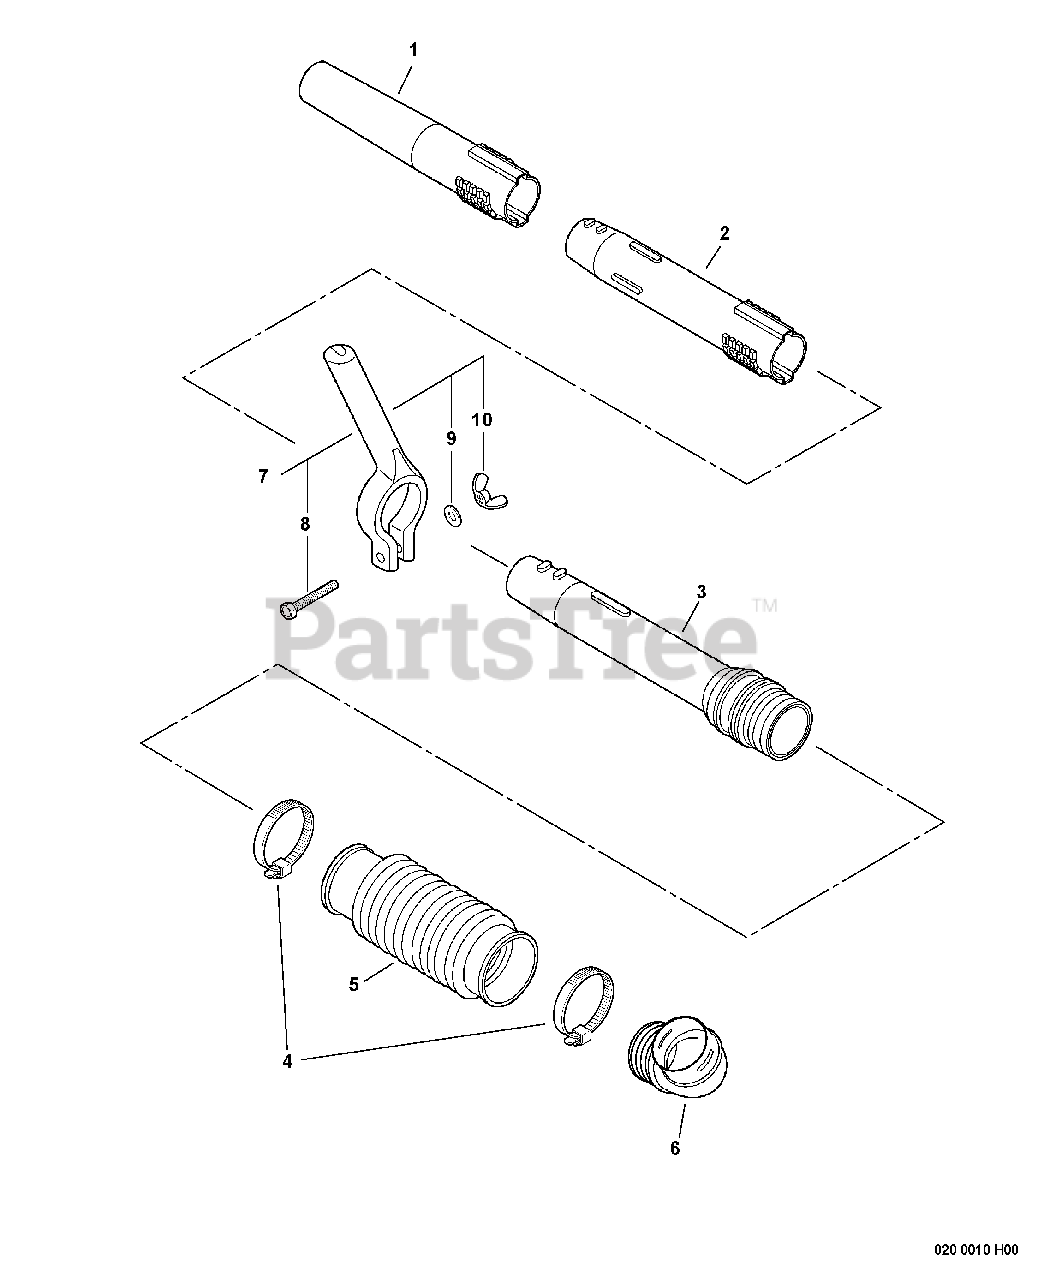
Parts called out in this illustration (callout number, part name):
1	TUBE, BLOWER - STRAIGHT NOZZLE
2	TUBE, BLOWER - STRAIGHT
3	TUBE, BLOWER - SWIVEL
4	CLAMP, HOSE
5	TUBE, BLOWER - FLEXIBLE
6	TUBE, BLOWER - ELBOW
7	TUBE MOUNT HANDLE
8	BOLT - 6X45
9	WASHER - 6
10	WINGNUT - 6
